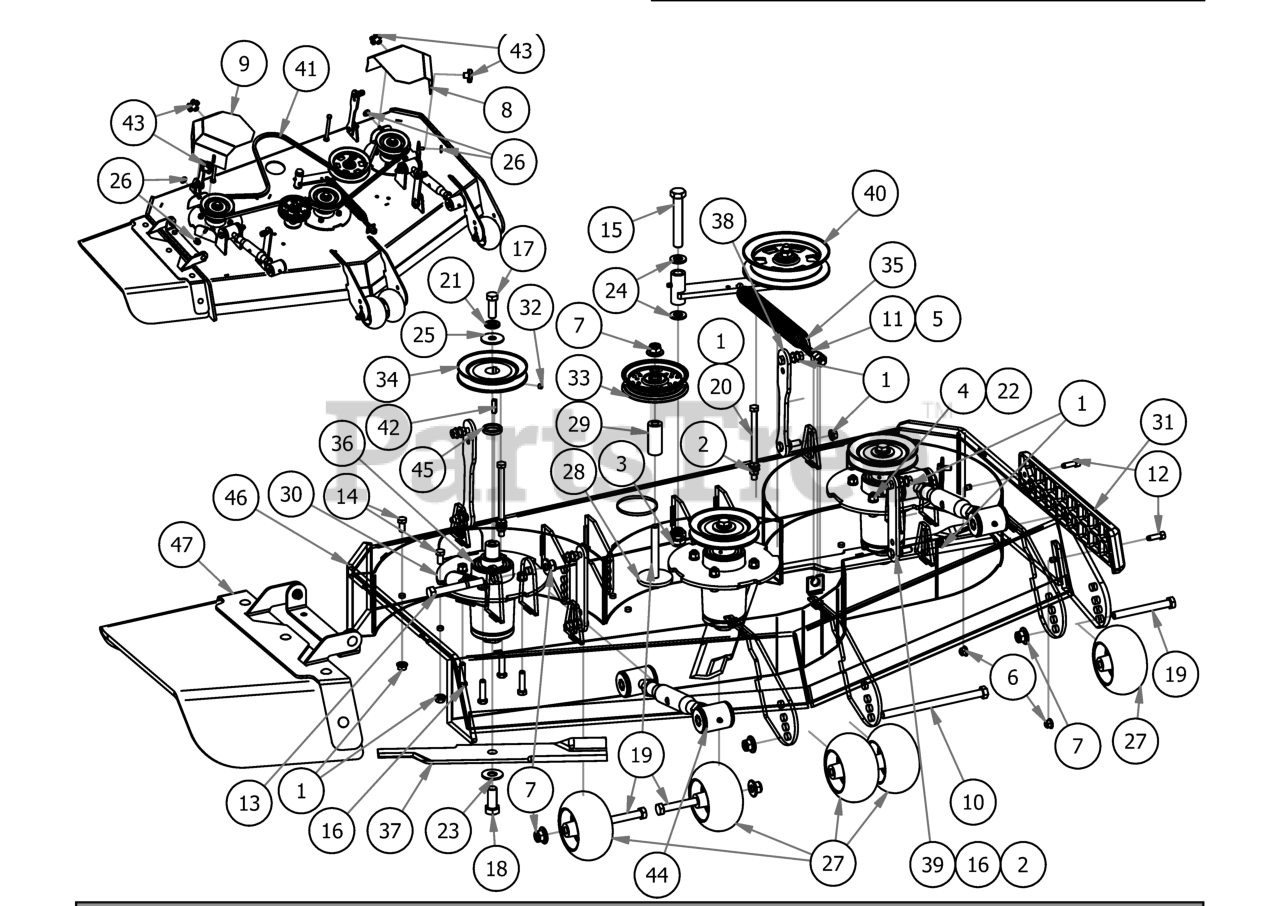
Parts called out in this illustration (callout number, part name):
1	3/8-16 HEX SERRATED FLANGE NUT HARD/ZINC
2	3/8" Nylock Flange Nut
3	5/8-11 Nylon Insert Jam Half Nut
4	3/8" Hex Nut
5	1/2" Hex Nut
6	5/16" Nylon Flange Nut
7	1/2-13 NYLON INSERT FLANGE LOCKNUT ZINC
8	2019 Stand On 48" Pulley Cover Trim
9	2019 Stand On 48" Pulley Cover Discharge
10	1/2-13 x 8 Hex Bolt Grade 5
11	All Thread-Pump Idler Tensioner
12	5/16-18 x 1 GR 5 Hex Bolt Zinc
13	1/2" x 4" Bolt (Grade 8)
14	3/8" x 3/4" Hex Bolt
15	5/8" x 4" Hex Bolt
16	3/8-16 X 1-1/2 HEX CAP SCREW (GR.5) ZINC
17	1/2"-20 x 1 1/2 - Grade 5 Fine Thread Bolt
18	5/8 x 1 1/2 Grade 8 Hex Bolt (Fine)
19	1/2" x 4 1/2" Bolt
20	3/8-16 x 5 1/2 Hex Bolt
21	1/2" Lock Washer Zinc
22	3/8" Lock Washer
23	5/8'' Flat Washer
24	.630 ID Plastic Washer
25	1/2" Belleville Washer
26	.360 ID Plastic Washer-Black
27	2019 Deck Wheel
28	MZ Deck Idler Spacer
29	2019 Revolt Stationary Idle Spacer
30	Deck Spindle Support Plate
31	REVISED TRIM BUMPER_20180226
32	5/16 Set Screw
33	4 3/4 Idler Pulley - ABFI-76
34	5" Spindle Deck Pulley
35	2019 Outlaw Gen2 Deck Spring
36	Spindle Assembly
37	16 1/4" Bad Boy Blade
38	2019 Stand-On Rear Deck Hanger
39	2019 Stand on deck hanger_front
40	2019 Revolt Deck Idler Assembly
42	1/4" x 1" Key
43	5/16" Knob
44	Turnbuckle
45	Spacer, 1x1.375x.25
46	2019 48 Stand On Deck Weldment
47	2019 Outlaw Gen2 Chute Assembly
